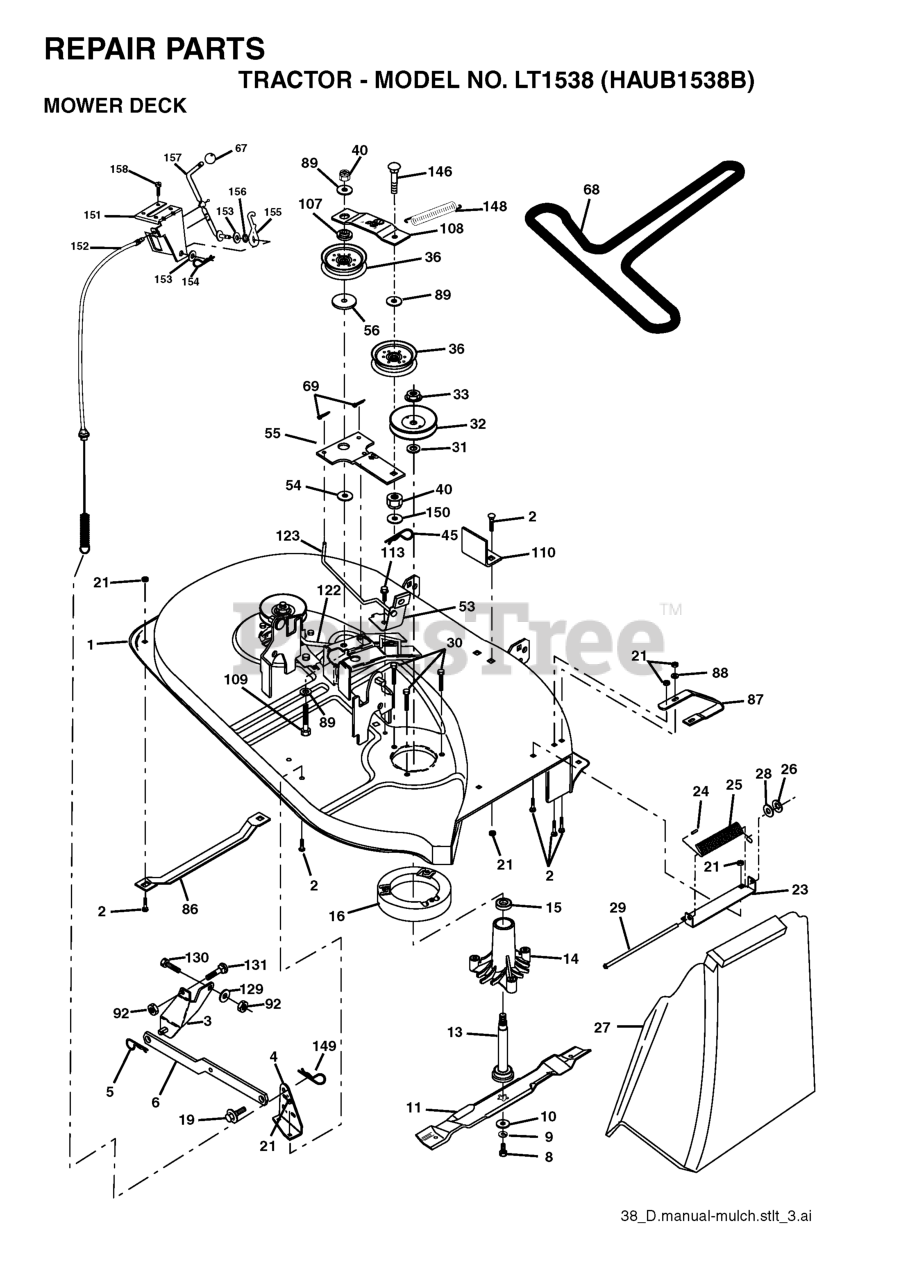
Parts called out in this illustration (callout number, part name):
1	MOWER HOUSING ASM
2	RP BOLT 5/16-18 X3/4 ZN/YEL GR
3	BRKT ASM SWAY BAR
4	BRACKET DECK SWAY BAR 38/42"
5	RETAINER-SPRNG RB
6	BAR SWAY DECK
8	BLADE BOLT
9	LOCKWASHER
10	WASHER.BLADE
11	BLADE.HI.LIFT.38"
13	SHAFT ASM VENT
14	HOUSING.MANDREL.VENTED (MACHD)
16	STRIPPER.MANDREL.ROUND.BLACK
19	BOLT SHD 5/16-18
21	LOCKNUT
23	BRACKET, DEFLECTOR
24	CAP-SLEEVE LT
25	SPRING TORSION
26	NUT PUSH M
27	SHIELD, DEFLECTOR
28	Washer 11/32 x 5/8 x 16 Ga SD
29	ROD-HINGE T
30	SCREW, WASHER HEAD
31	WASHER
32	PULLEY MANDREL
33	NUT, FLG TOPLOCK 9/16"
36	FLAT IDLER PULLEY
45	RETAINER M
53	BRAKE ASSEMBLY
56	SPACER.RETAINER.MOWER
67	KNOB T (3/8 HOLE)
68	V-BELT TRIPATH
69	COTTER PIN
86	RUNNER-LH M
87	RUNNER.RH.38
88	WASHER M
89	WASHER GT
96	LOCKNUT
97	Bolt, Hex Head 3/8-16 x 1-1/4
107	SPACER.IDLER.ARM
108	STIFFENER.IDLER.ARM
109	Bolt Hex Fin 3/8-16 UNC x 2-1/2
110	UPSTOP DECK FRONT 38"
113	SCREW 5/16"
122	BRAKE ROD LH
123	ROD.BRAKE.MANDREL.RH
146	BOLT, CARRIAGE IDLER
148	IDLER RETURN SPRING
149	SPRING.RETAINER.YELLOW.ZINC
151	BRACKET.CLUTCH.CABLE
152	CLUTCH CABLE 38"/46"
153	WASHER FLAT 3/8"
154	SPRING RETAINER
155	SPRING RETENTION LEVER
156	SPACER.CLUTCH.CABLE
157	ROD CLUTCH CABLE 3/8"
158	SCREW
